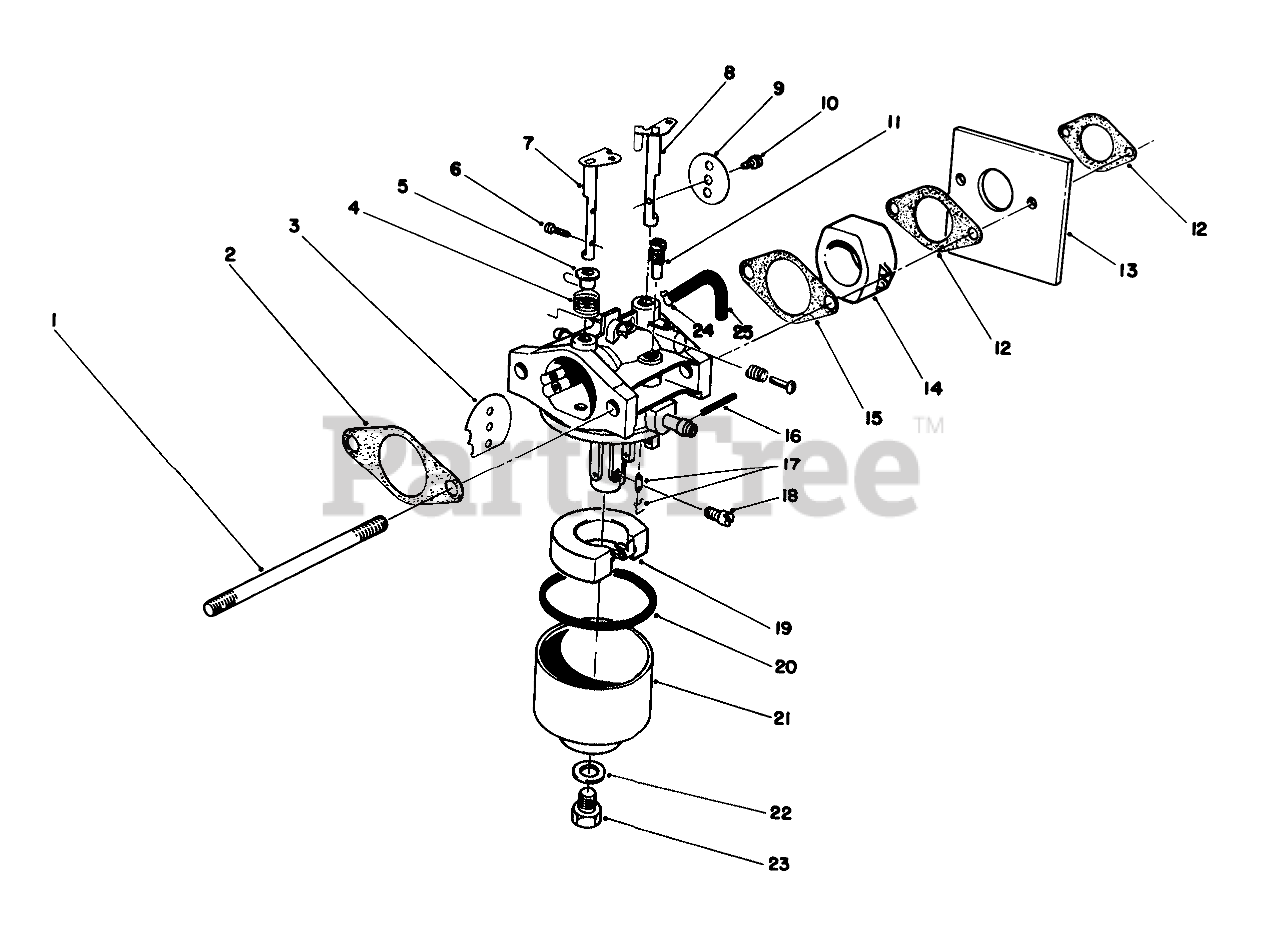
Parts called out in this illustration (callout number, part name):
1	STUD-CARBURETOR
2	GASKET-AIR CLEANER
3	PLATE
4	SPRING
5	BUSHING
6	SCREW
7	SHAFT-CHOKE
8	SHAFT
9	PLATE
10	Screw-Throttle
11	PILOT JET
12	GASKET
13	SHIELD-CARBURETOR
14	INSULATOR-CARBURETOR
15	GASKET-CARB
16	Pin
17	NEEDLE
18	JET-MAIN
19	FLOAT
20	GASKET
21	Bowl-Float
22	GASKET
23	Bolt
24	CLAMP
25	VENT TUBE
